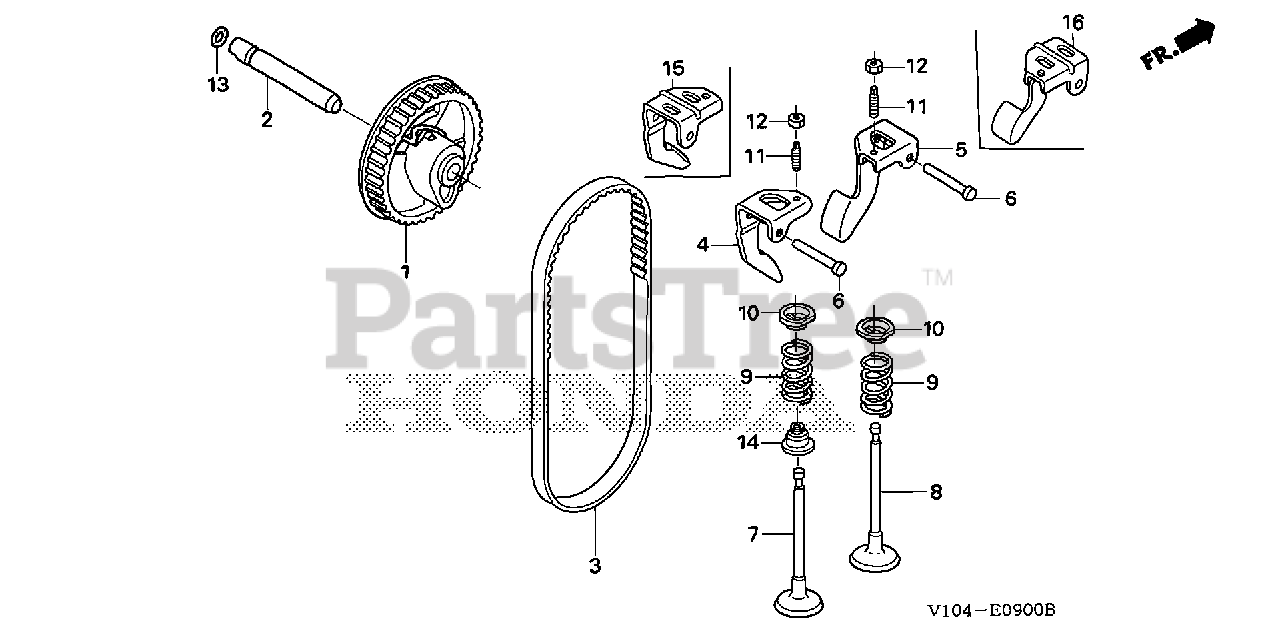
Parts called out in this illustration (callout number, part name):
1	PULLEY, CAMSHAFT
2	SHAFT, CAM PULLEY
3	BELT, TIMING (84HU6 G-200)
6	SHAFT, ROCKER ARM
7	VALVE, IN. (TECHNOSTAR)
7	VALVE, IN.
8	VALVE, EX. (L8E)
8	VALVE, EX. (C8E)
9	SPRING, VALVE
10	RETAINER, VALVE SPRING
11	SCREW, TAPPET ADJUSTING
12	NUT, TAPPET ADJUSTING
13	O-RING (6.8X1.9) (ARAI)
14	SEAL, VALVE STEM
15	ARM, IN. VALVE ROCKER
16	ARM, EX. VALVE ROCKER
